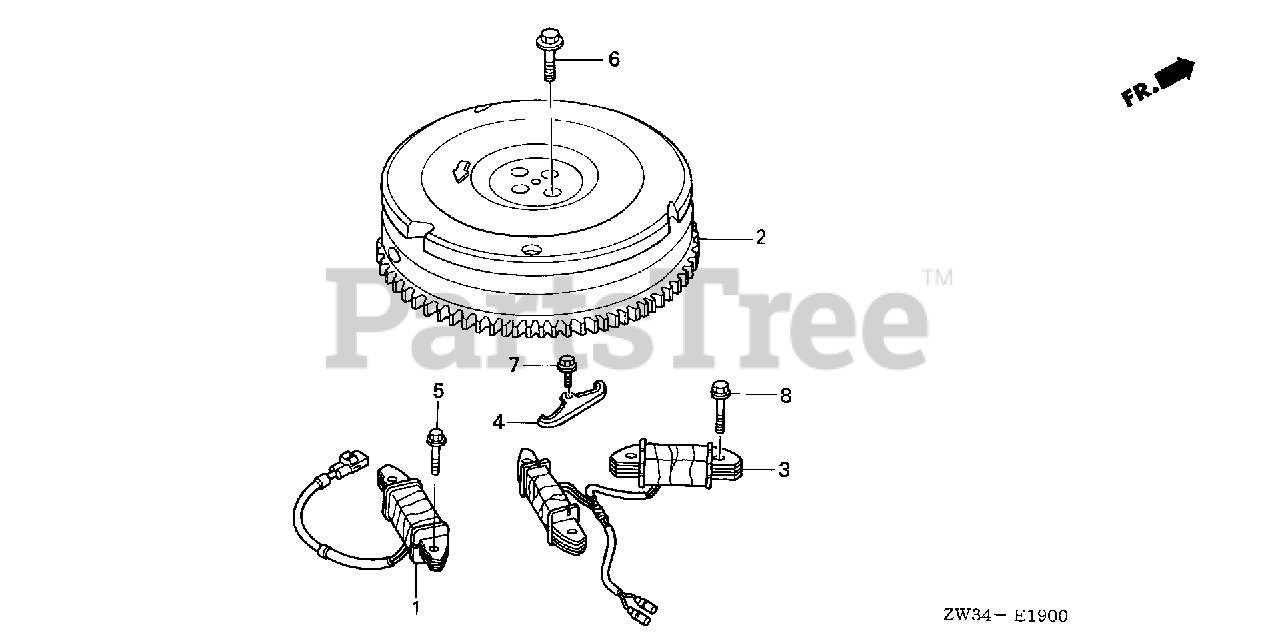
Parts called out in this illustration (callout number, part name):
1	COIL ASSY., POWER
2	FLYWHEEL *TBLACK* (BLACK)
3	COIL ASSY., CHARGE (12V/10A)
4	HOLDER, WIRE (B)
5	BOLT, FLANGE (6X22) (CT200)
6	BOLT, FLANGE (10X25)
7	BOLT, FLANGE (6X12)
8	BOLT, FLANGE (6X32) (CT200)
